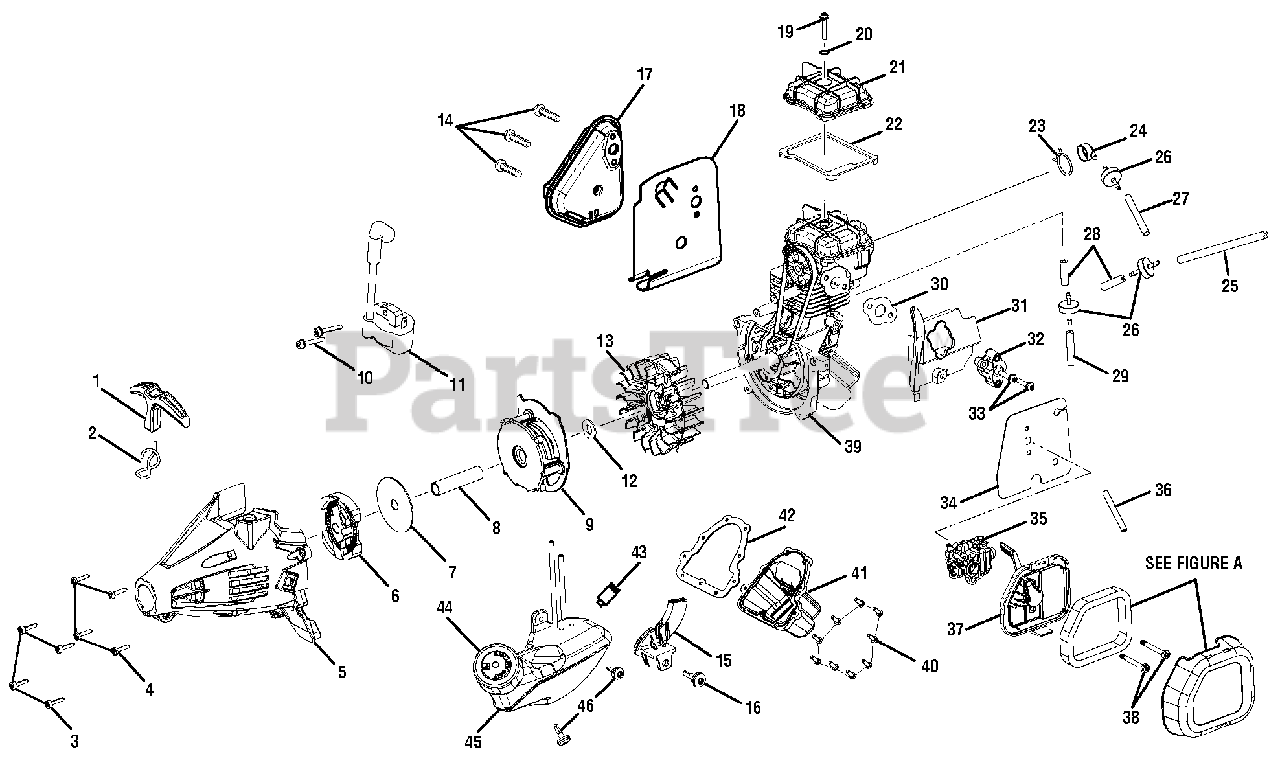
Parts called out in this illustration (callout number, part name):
1	Starter Grip
2	Starter Rope
3	Screw (M4 x 18 mm, T20 Torx Soc. Hd.)
4	Screw (M4 x 16 mm, T20 Torx Soc. Hd.)
5	Starter Housing Assembly
6	Clutch Assembly
7	Washer (ID9.63 x OD50.75 x 1.10t)
9	Starter Housing Assembly
10	Screw (M4 x 19 mm, T20 Torx Pan Hd.)
11	Ignition Module
12	Washer (ID9.75 x OD20 x 1.6t)
13	Flywheel Assembly
14	Screw (M5 x 38 mm, T25 Torx Truss Hd.)
15	Throttle Cable Guide
16	Shoulder Screw (M4 x 19 mm, T25 Torx Truss Hd.)
17	Muffler Assembly
18	Muffler Gasket
19	Screw (M4 x 27 mm, T20 Torx Truss Hd.)
21	Cam Cover
22	Cam Cover Gasket
23	Wire Clamp
24	Breather Fitting
25	Breather Hose (120 mm)
26	Check Valve
27	Shield Sleeve (M6 x 50 mm)
28	Breather Hose (24 mm)
29	Breather Hose (34 mm, Crankcase)
30	Heat Dam Gasket
31	Air Baffle
33	Screw (M5 x 23 mm, T25 Torx Pan Hd.)
34	Heat Shield w/Gasket (Carburetor)
35	Carburetor
36	Breather Hose (50 mm)
37	Air Box Base Assembly
38	Screw (M5 x 44 mm, T20 Torx Hd.)
39	Short Block Assembly
40	Screw (M4 x 12 mm, T20 Torx Hd.)
42	Oil Pan Gasket
43	Fuel Filter
45	Fuel Tank w/Cap
46	Shoulder Screw (M4 x 14 mm, T25 Torx Truss Hd.)
